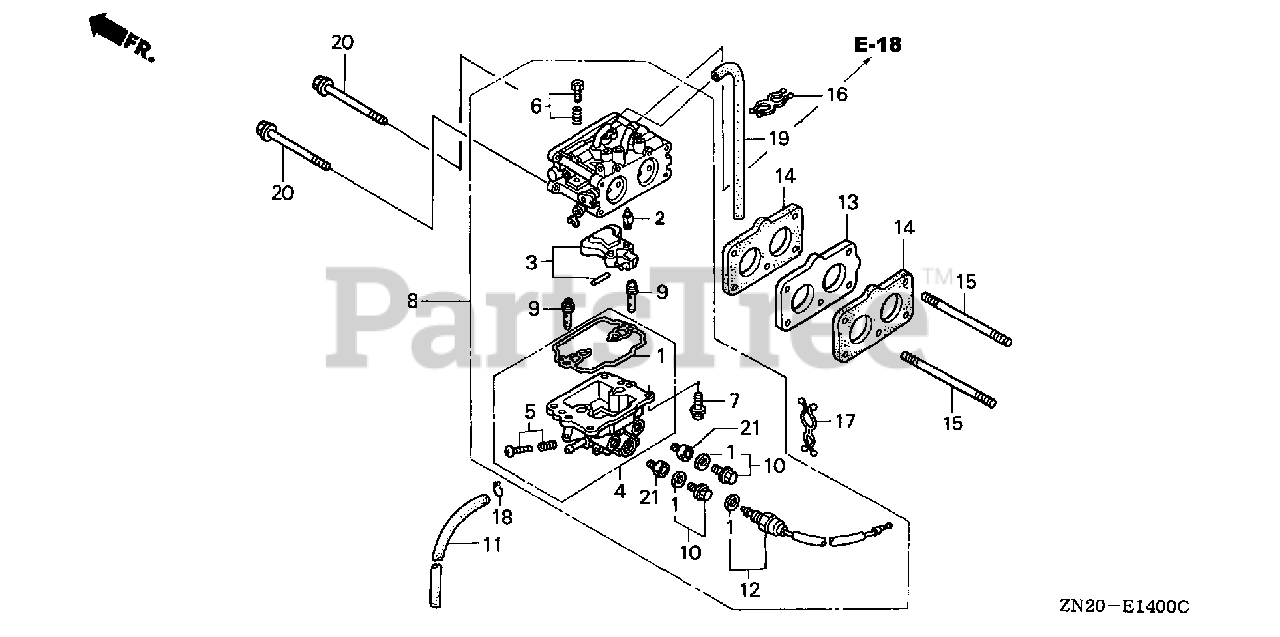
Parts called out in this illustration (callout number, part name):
1	GASKET SET (ADVENTURE GREEN) (CARBURETOR NO.)
2	VALVE, FLOAT (ADVENTURE GREEN) (CARBURETOR NO.)
3	FLOAT SET (ADVENTURE GREEN) (CARBURETOR NO.)
4	CHAMBER SET, FLOAT (ADVENTURE GREEN) (CARBURETOR NO.)
5	SCREW SET, DRAIN (ADVENTURE GREEN) (CARBURETOR NO.)
6	SCREW SET (ADVENTURE GREEN) (CARBURETOR NO.)
7	SCREW-WASHER (ADVENTURE GREEN) (CARBURETOR NO.)
8	CARBURETOR ASSY. (BK02A A)
9	JET, SLOW (#54) (ADVENTURE GREEN) (CARBURETOR NO.)
10	PLUG SET (ADVENTURE GREEN) (CARBURETOR NO.)
11	TUBE, DRAIN
12	VALVE ASSY., SOLENOID (NIKKI) (ADVENTURE GREEN) (CARBURETOR NO.)
13	INSULATOR, CARBURETOR
14	GASKET, CARBURETOR
15	BOLT, STUD (6X108)
16	CLIP, WIRE HARNESS
17	CLIP, PURSE LOCK
18	CLIP, TUBE (B8)
19	BULK HOSE, VACUUM (4.5X1000) (4.5X540)
20	BOLT, FLANGE (6X95)
21	JET, MAIN (#104) Use up to Engine SN TB02A A.
21	JET, MAIN (#108) Use up to Engine SN TB02A A.
21	JET, MAIN (#112) (ADVENTURE GREEN) (CARBURETOR NO.)
